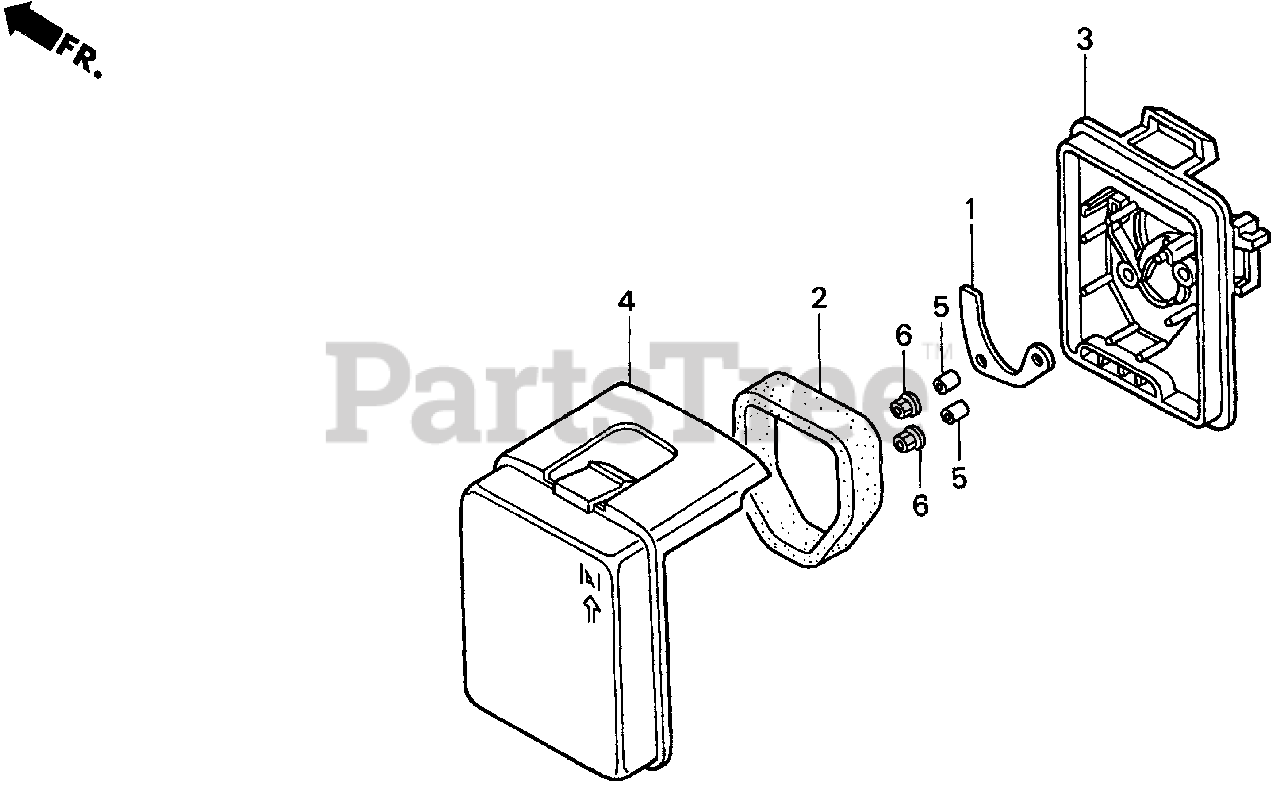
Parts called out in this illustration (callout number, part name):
1	PLATE, OIL TRAP
2	ELEMENT, AIR CLEANER
3	HOUSING, AIR CLEANER *NH1* (BLACK)
4	COVER, AIR CLEANER *NH1* (BLACK)
5	COLLAR, AIR CLEANER
6	NUT, FLANGE (5MM)
